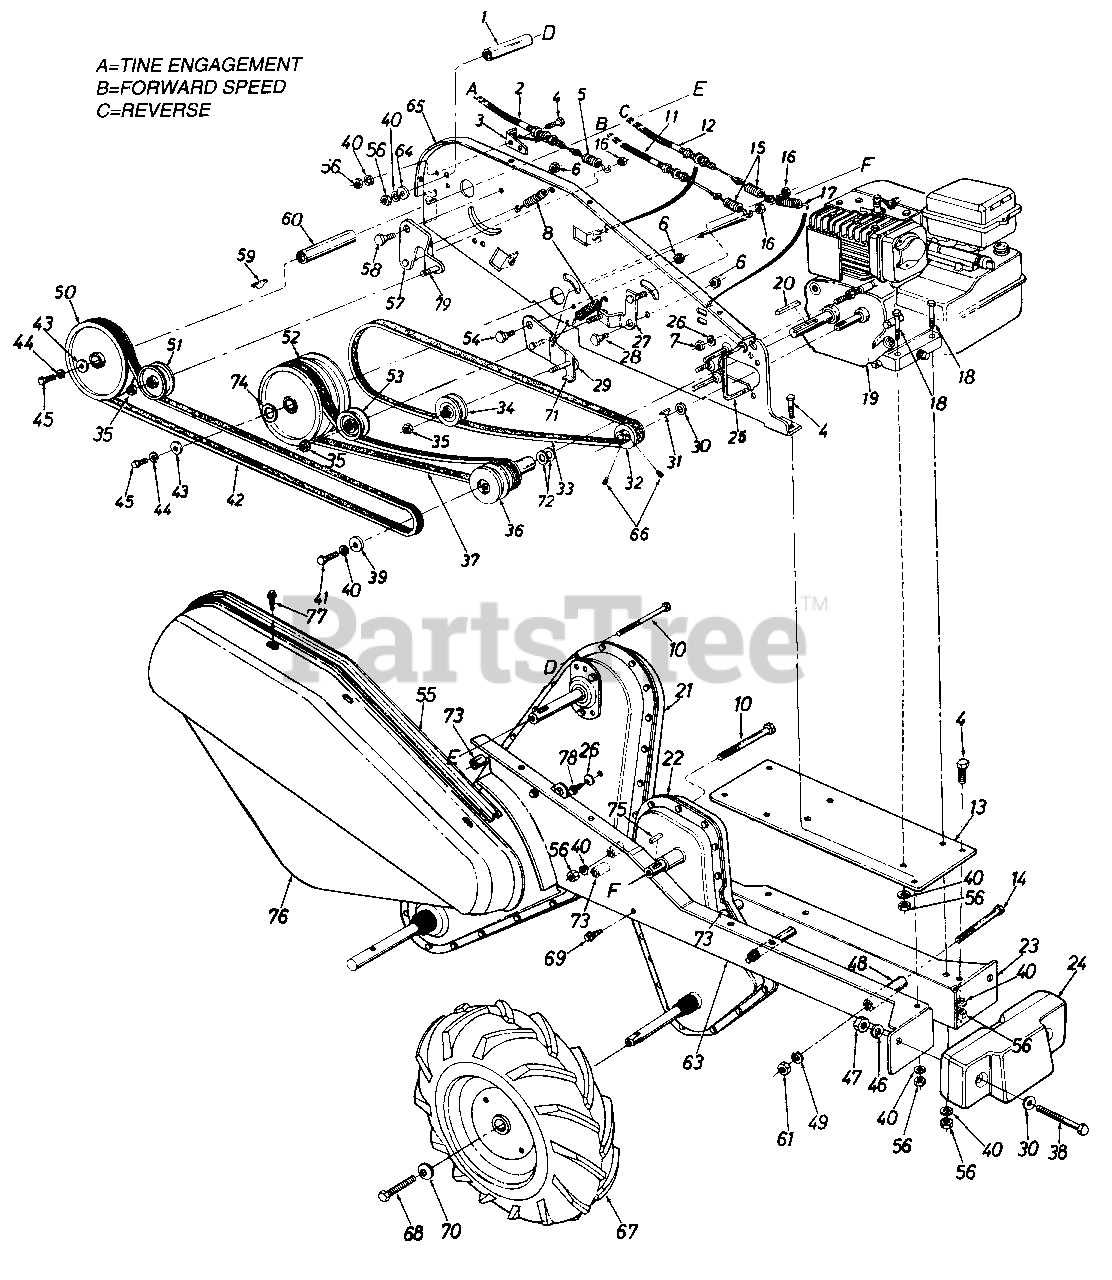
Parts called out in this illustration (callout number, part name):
1	Spacer .375" I.D. x .5" O.D. x 2" Lg.
2	Clutch Control Cable (Tines)
3	Clutch Cable Bracket
4	Hex Bolt 5/16-18 x .75" Lg.
5	Extension Spring .50" O.D. x 2.5" Lg.
6	Hex Cent. L-Nut 3/8-16 Thd.
7	Hex Nut 1/4-20 Thd.
8	Extension Spring .50" O.D. x 1.55" Lg.
10	Hex Bolt 5/16-18 x 3" Lg.
11	Clutch Control Cable 42" Lg. (Forward)
12	Clutch Control Cable 42" Lg. (Reverse)
15	Springs
16	Hex Cent. L-Nut 1/4-20 Thd.
17	Extension Spring .41" O.D. x 2.05" Lg.
18	Hex Bolt 5/16-18 x 1.5" Lg.
19	Engine
20	Sq. Key 3/16 x 1.00" Lg.
21	Chain Case Comp. - Tines
22	Chain Case Comp. - Wheels
25	Belt Keeper
26	Bell-Wash. .265" I.D. x .75" O.D.
29	Idler Brkt. Ass'y. (Wheel Forward)
30	Fl-Wash. .51" I.D. x 1.0"
31	#5 Hi-Pro-Key 1/8" x 5/8" Dia.
32	1/2" V-Pulley 2.25" O.D. x .503" I.D.
33	"V"-Belt
34	"V"-Belt Idler 2.62" O.D.
35	Hex Ins. L-Nut 3/8-24 Thd.
36	1/2" "V"-Pulley Ass'y.
37	"V"-Belt
38	Hex Bolt 1/2-13 x 4" Lg.
39	Fl-Wash. .344" I.D. x 1.125"
40	L-Wash. 5/16" I.D.
41	Hex Bolt 5/16-24 x 1.00" Lg.
42	"V"-Belt
43	Fl-Wash. 1/4" I.D. x .93" O.D.
44	L-Wash. 1/4" I.D.
45	Hex Bolt 1/4-28 x .75" Lg.
46	L-Wash. 1/2" I.D.
47	Hex Nut 1/2-13 Thd.
48	Spacer .38" I.D. x .62" O.D. x 2.18" Lg.
49	L-Wash. 3/8" I.D.
50	Fl-Pulley w/Flanges 6" O.D.
51	Fl-Idler w/Flanges 3.75" O.D.
52	Double Fl-Pulley 5/8" I.D.
53	Fl-Idler w/Flanges 2.12" O.D.
54	Shld. Bolt .500" Dia. x .170" Lg.
55	Flange Extension
56	Hex Nut 5/16-18 Thd.
59	#61 Hi-Pro-Key 3/16" x 5/8" Dia.
60	Spacer .647" I.D. x 2.75" Lg.
61	Hex Nut 3/8-24 Thd.
65	Side Plate Ass'y.
66	Set Scr. 1/4-28 x .25" Lg.
67	R.H. Wheel Ass'y. Comp. 13 x 5
68	Hex Bolt 5/16-24 x .62" Lg.
69	Hex Self-Tap Scr. 5/16-24 x .5" Lg.
70	Bell-Wash. 5/16" I.D.
71	Belt Keeper Brkt.
72	Fl-Wash. .76" I.D. x 1.5"
73	Spacer .326" I.D. x .47" O.D. x .96" Lg.
74	Fl-Wash. 5/8" I.D. x 1" O.E.
75	Sq. Key 3/16 x .75" Lg.
78	Hex Wash. S-Tap Scr. 1/4-20 x .38" Lg.
79	Hex Bolt 3/8-24 x 1.25" Lg.
